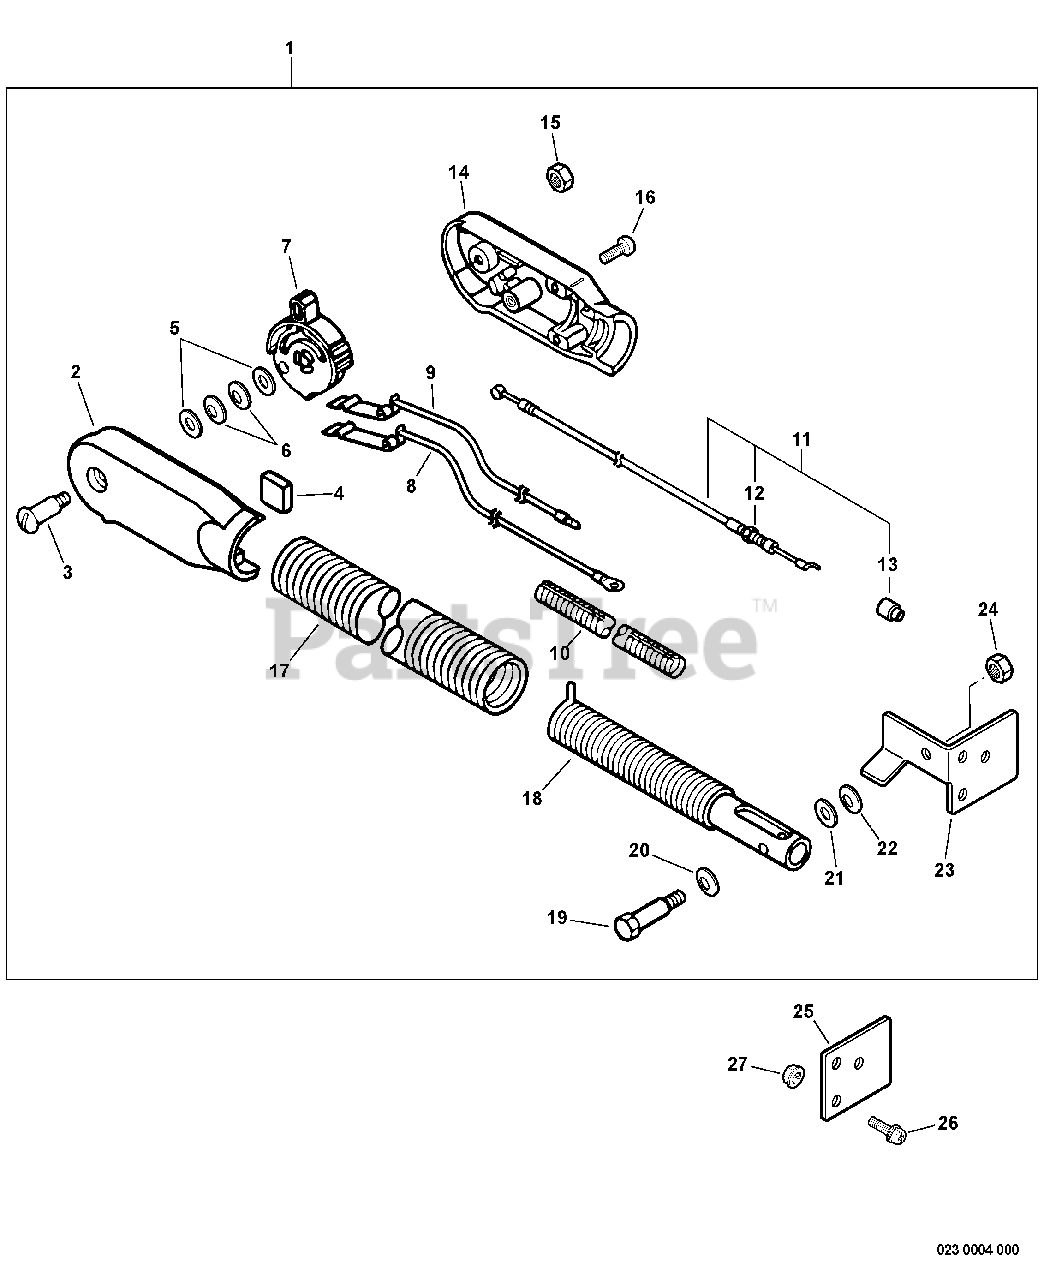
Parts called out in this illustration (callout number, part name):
1	HIP MOUNT THROTTLE CONTROL KIT
2	HANDLE, CONTROL - LEFT
3	SCREW - 4
4	PAD, FOAM
5	WASHER - 6
6	WASHER - SPRING
7	LEVER, THROTTLE CONTROL
8	LEAD - GROUND
9	LEAD - IGNITION
10	TUBE, PROTECTIVE - CORRUGATED
11	THROTTLE CABLE ASSY
12	LOCKNUT - 6
13	CAP, DUST
14	HANDLE, CONTROL - RIGHT
15	LOCKNUT - 4
16	SCREW - 5X20
18	TUBE, SPRING
19	BOLT - 6
20	WASHER - SPRING
21	WASHER - 8
22	WASHER - 8
23	BRACKET
24	LOCKNUT - 1/4"
26	SCREW - 5X16
27	NUT - 5 -- FLANGE
